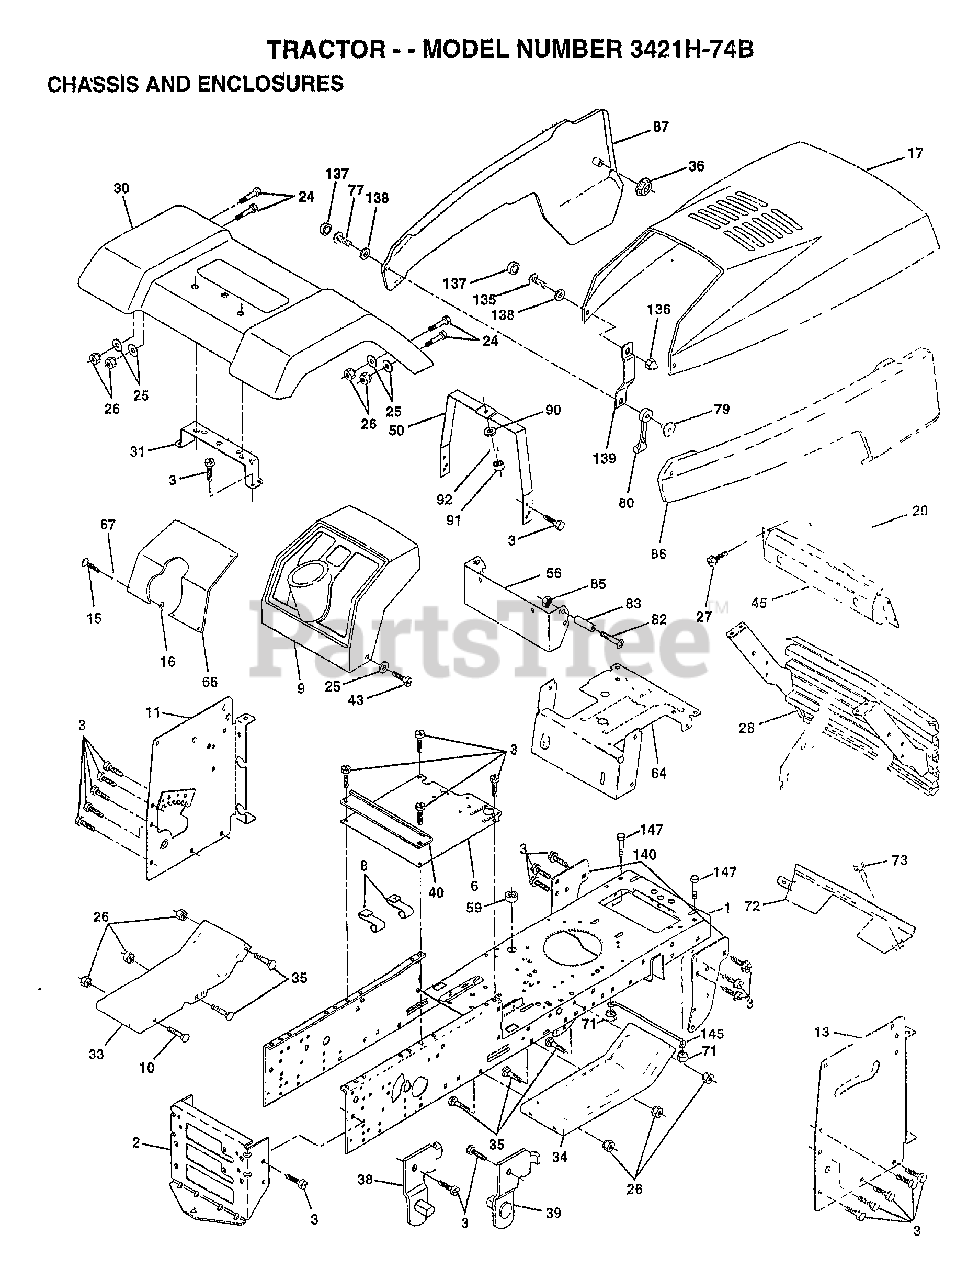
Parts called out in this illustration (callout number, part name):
1	CHASSIS ASM
3	SCREW
6	SADDLE
8	"CLIP,INSULATOR"
9	DASHBOARD BLACK
11	PANEL.DASH.LH.
13	PANEL.DASH.RH.
15	SCREW
24	BOLT
25	WASHER
26	NUT
28	GRILLE ASM PNT
29	LENS.BAR.CLEAR
31	BRACKET SUPT FEND
33	FOOTREST.LH.LT/GT
34	FOOTREST.RH.LT/GT
35	BOLT
36	PAL NUT LT
38	BRACKET ASM LH
39	BRACKET ASM RH
40	SPACER FENDER LT
43	SCREW GTV
45	BEZEL.ASM.
50	DASH.SUPT.YP/HUSQ
56	EXT DASH LTYT
64	DASH.LOWER.LT
66	"PLATE DASH,SLKSCR"
67	WASHER
72	STRAP.GRILLE.424
73	SCREW CRT
77	SCREW
79	WELDNUT
80	HOOD LATCH T
82	SCREW
83	SPACER LT
90	WASHER PM
92	LOCKWASHER
135	SCREW.10-24X3/8.
136	ACORN NUT RB
137	SNAP CAP LT
138	WASHER LT
139	BKT.SPT.HOOD/PANL
140	BRKT SUSPENSION
145	"ROD POVOT,CHASSIS"
147	BOLT LT
